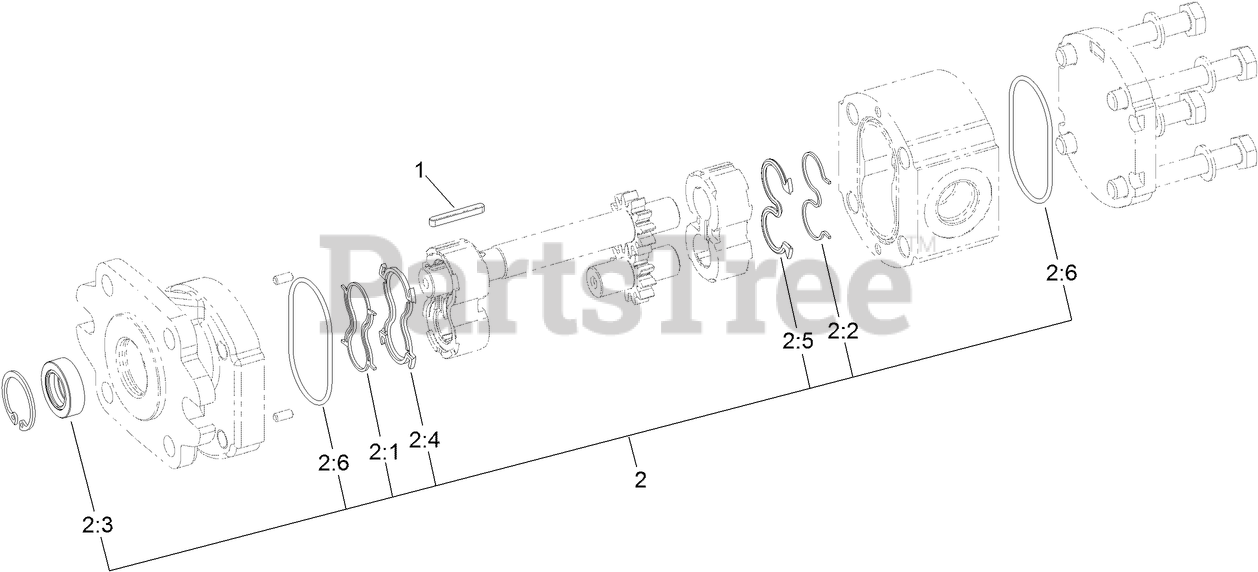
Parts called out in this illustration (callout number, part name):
1	KEY-SQUARE
2	SEAL KIT
2:1	SEAL-ANTI EXTRUSION
2:2	SEAL-ANTI EXTRUSION
2:3	SEAL-SHAFT
2:4	SEAL-UPPER
2:5	SEAL
2:6	O-RING
